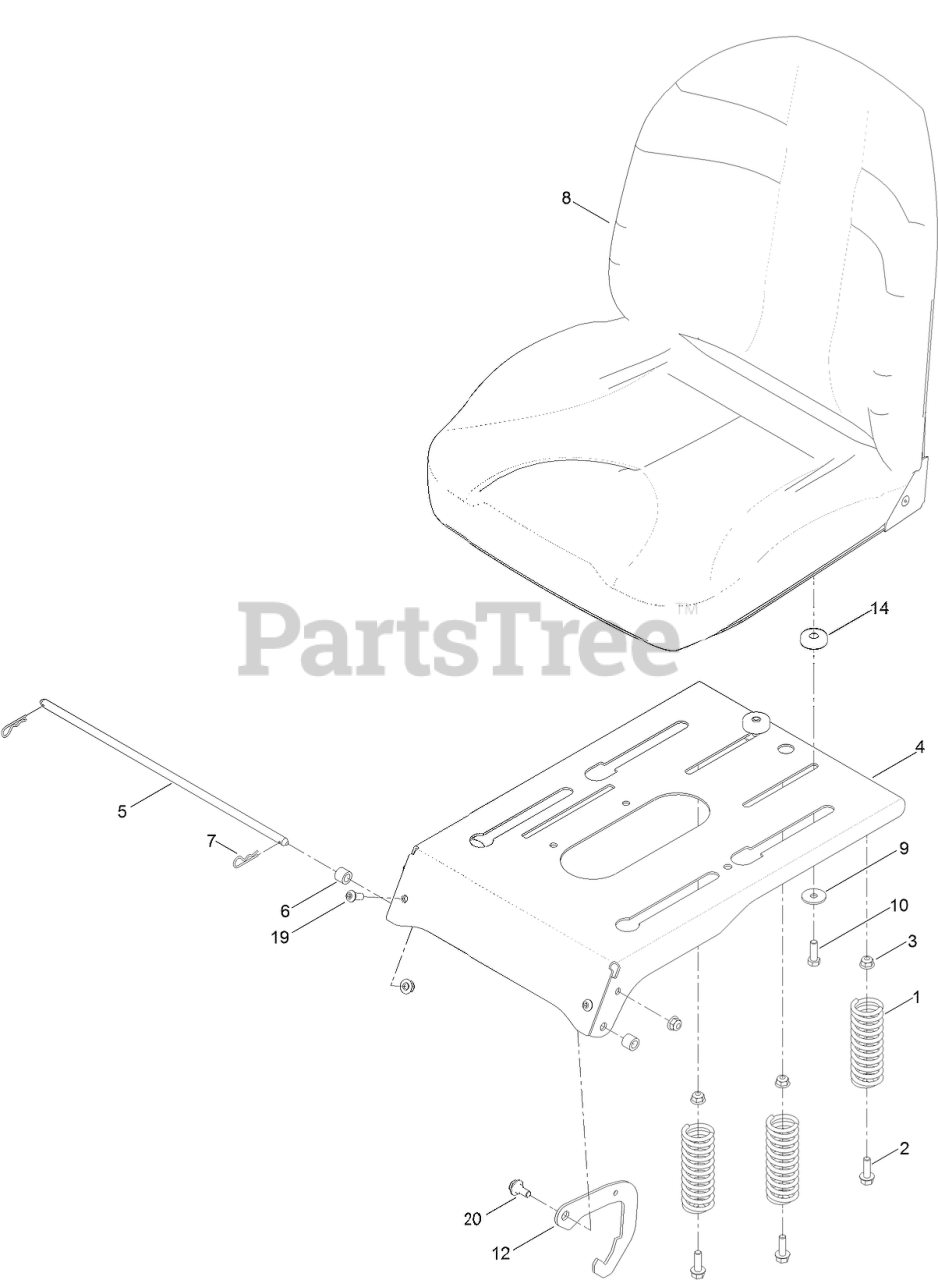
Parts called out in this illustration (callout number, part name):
1	SPRING-COMPRESSION
2	SCREW-HHF
3	NUT-HF, NI
4	PAN-SEAT, DELUXE
5	ROD-STOP
6	BUSHING-LEVER, LIFT
7	PIN-COTTER
8	SEAT ASM
9	WASHER-PIVOT
10	SCREW-HH
12	LATCH-SEAT
14	BUSHING-SLIDE, SEAT
19	SCREW-HSBH
20	SCREW-SHOULDER
